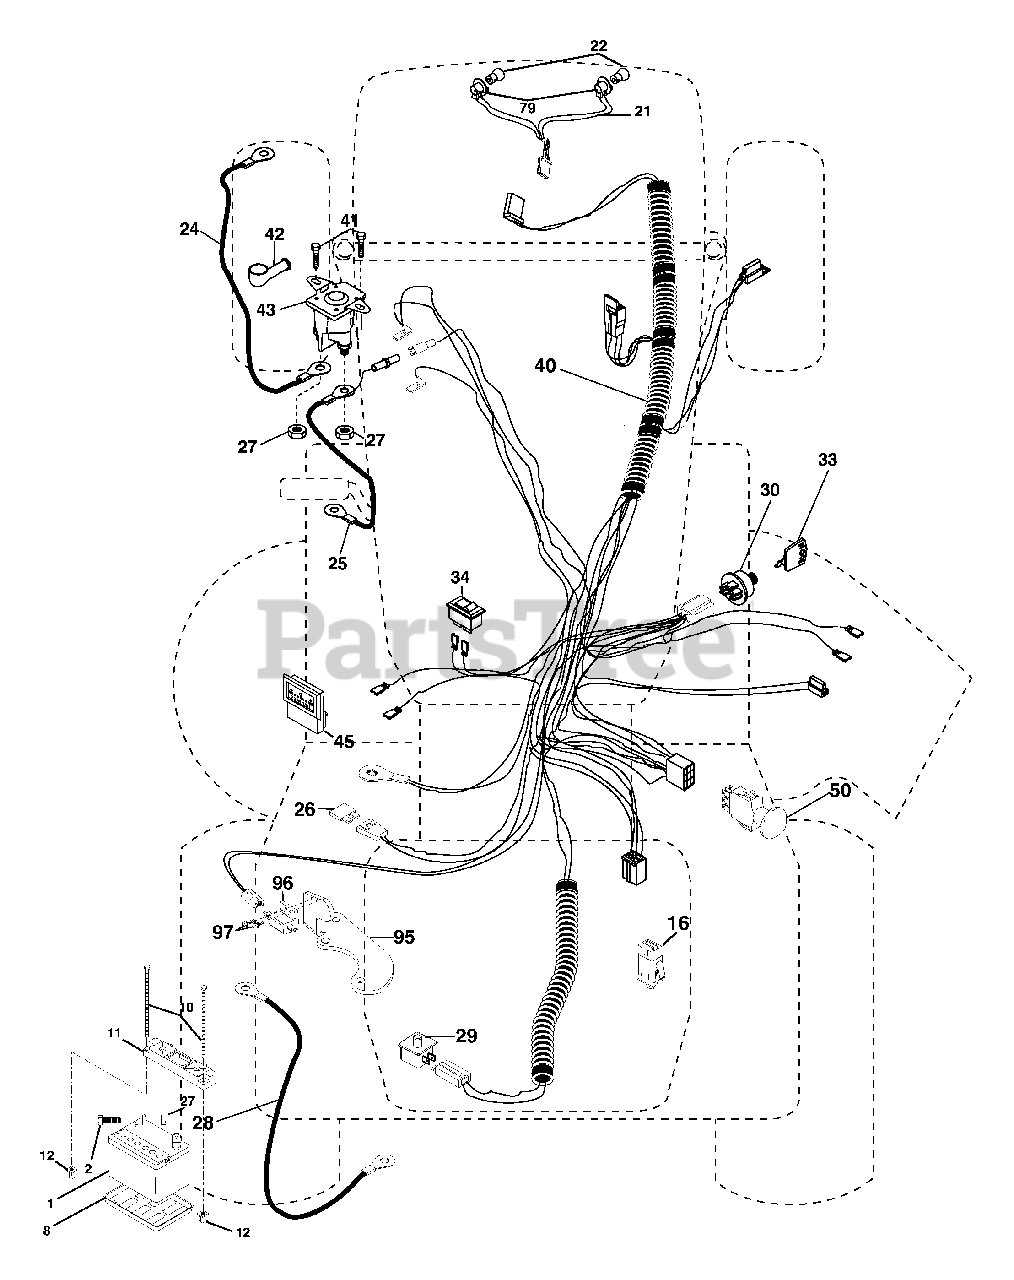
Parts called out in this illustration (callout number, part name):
1	Battery
2	Bolt Hex Head 1/4-20 x 3/4
8	Tray, Battery
10	Bolt 1/4-20 x 7.5 Zinc
11	Hold down Battery Dash Mount
12	Nut Push Nylon 1/4"
16	Switch Interlock
21	Harness Socket Light W/4152J
22	Bulb Light
24	Cable Battery
25	Cable Battery
26	Fuse
27	Nut Keps Hex 1/4-20 Unc
28	Cable, Ground
29	Switch, Seat
30	Switch, Ign
33	Key, Ignition
34	Switch Light/Reset
40	Harness Ign.
41	Screw Thd Cut 1/4-20 x 1/2
42	Cover, Terminal
43	Solenoid
45	Ammeter
50	Switch, PTO
79	Socket Asm. Bulb
95	Bracket ROS
96	Switch Intek
97	Screw #10-24 x .50
